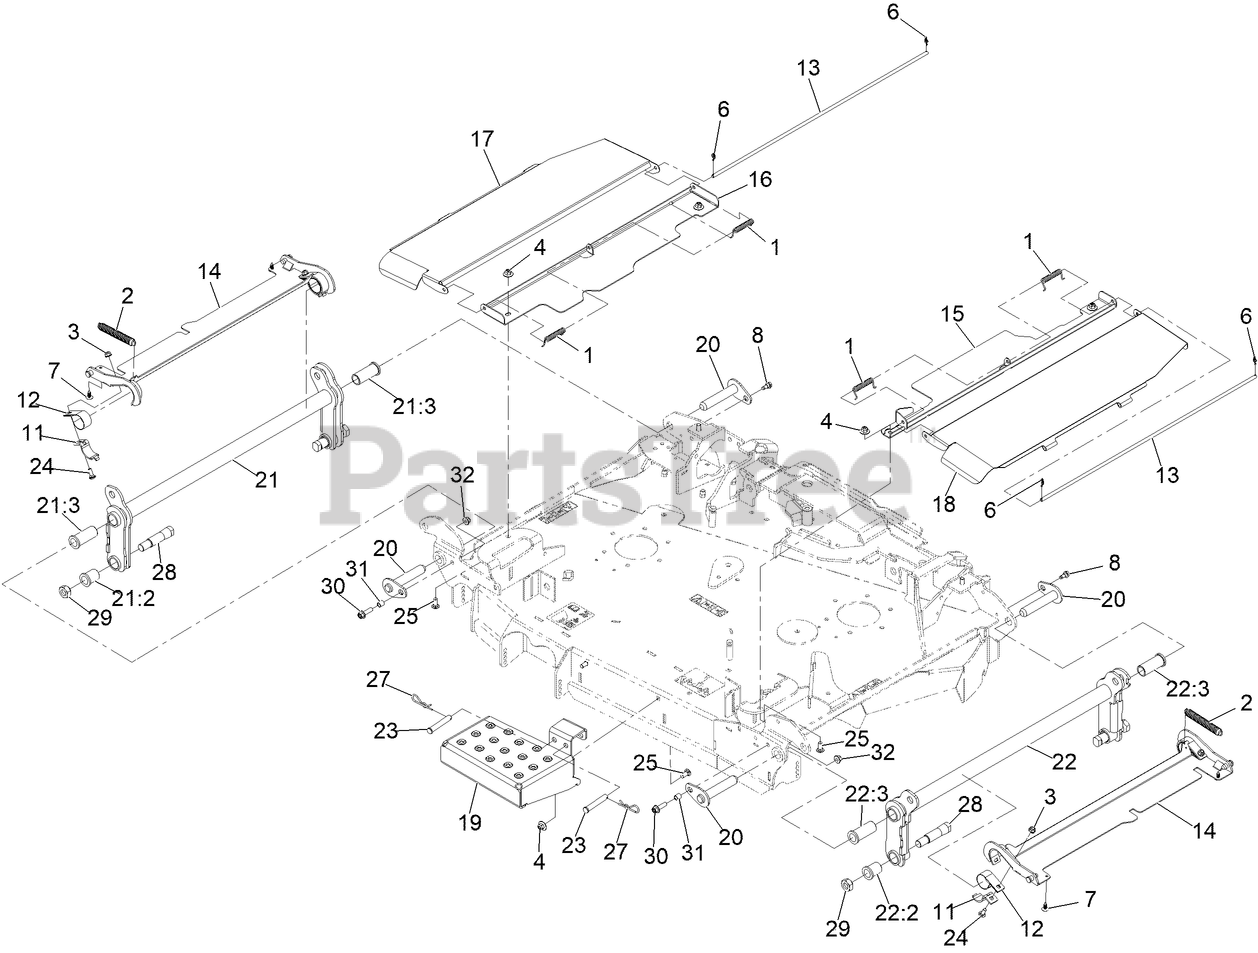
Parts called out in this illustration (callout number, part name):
1	SPRING-TORSION
3	NUT-HF, NI
4	Nut-Nyloc 3/8-16 Flg
6	PIN-COTTER, LOCKING
7	PLUG-PLASTIC
8	SCREW-SHOULDER
11	PLATE-RETAINER, BEARING
12	BEARING-STRAP, NYLON
13	COVER-ROD, PIVOT
14	COVER-WING
15	SHIELD-CENTER, LH
16	SHIELD-CENTER, RH
17	Panel-Shield Hinge, LH
18	Shield-Center, RH
19	Plate-Step
20	ASM-DECK PIN
21	ASM-RH FOLD ARM
21:2	BUSHING-FLANGED
21:3	BUSHING-FLANGED
22	ASM-LH FOLD ARM
22:2	BUSHING-FLANGED
22:3	BUSHING-FLANGED
23	PIN-CLEVIS
24	SCREW-CARR
25	BOLT-CARR
27	PIN-HAIR
28	BOLT-PIVOT PIN
29	NUT-LUG
30	SCREW, HHF
31	SPACER-TUBE, PUMP LINK
32	NUT-HF, NI
